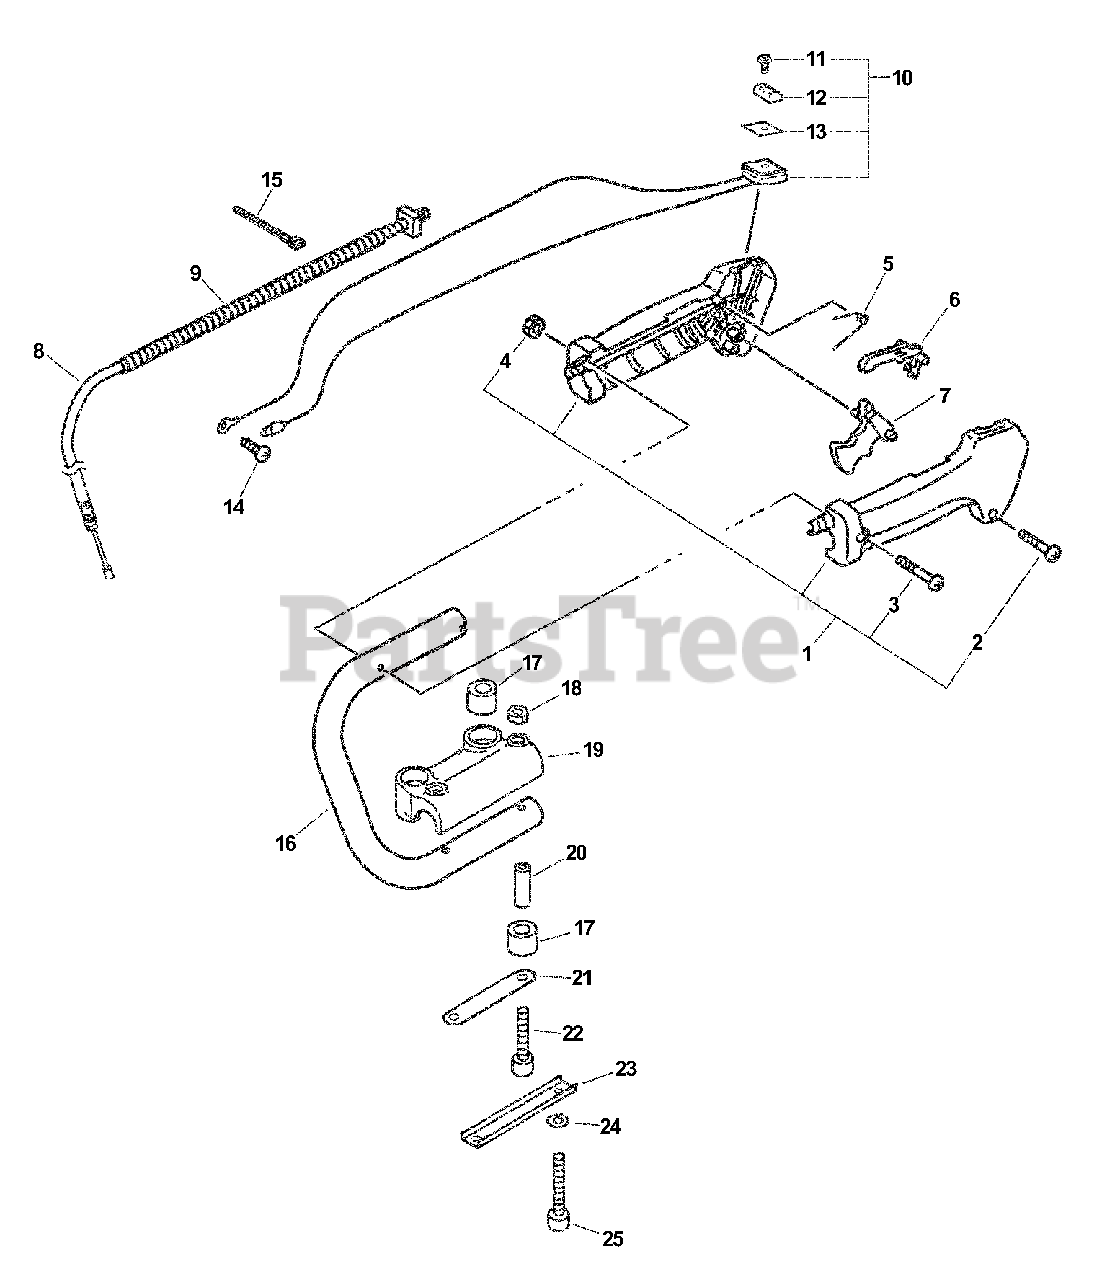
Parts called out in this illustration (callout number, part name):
1	CONTROL HANDLE KIT
2	SCREW 3×25
3	SCREW 5×30
4	NUT M5
5	SPRING, TORSION
6	LOCKOUT, THROTTLE
7	TRIGGER, THROTTLE
8	CABLE, THROTTLE
10	SWITCH, ON-OFF
11	SCREW 3×10
12	KNOB, SWITCH - ORANGE
13	LABEL, SWITCH
14	SCREW 5×10
15	TIE, CABLE
16	HANDLE, REAR
18	NUT M5
19	BRACKET, HANDLE - UPPER
20	SPACER
21	PLATE, EYE
22	BOLT 5×45
24	WASHER 5.5×18×1
25	BOLT M5×35
